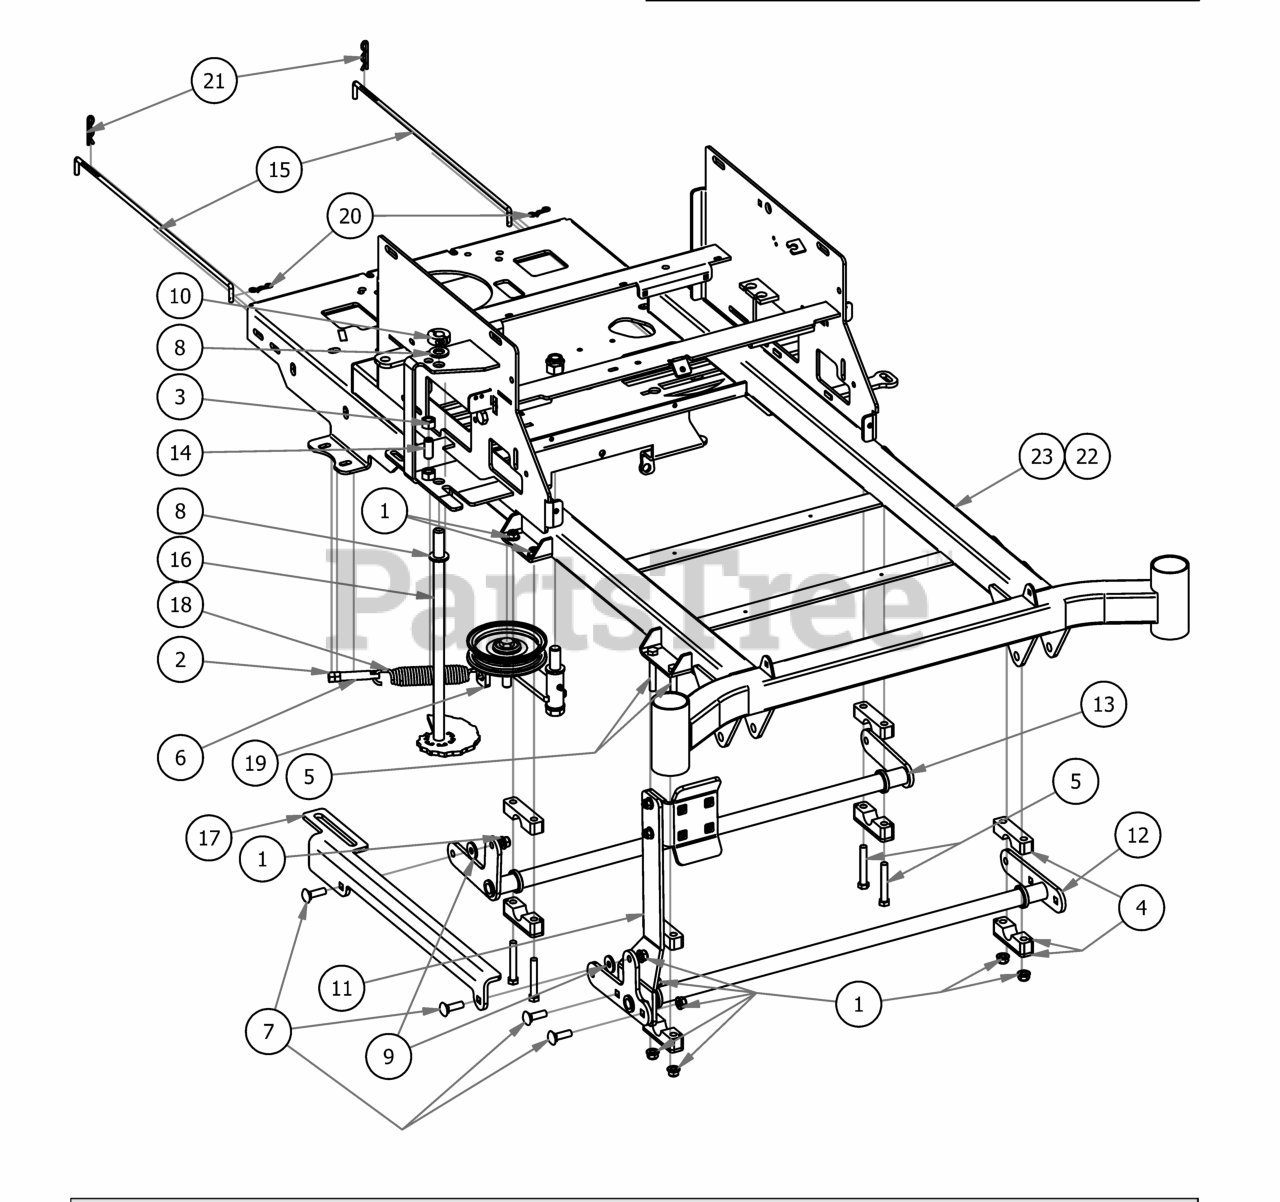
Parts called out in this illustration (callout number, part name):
1	3/8" Nylock Flange Nut
2	3/8-16 Hex Nut
3	1/2" Hex Nut
4	Pillow Block Kit
5	3/8-16 x 2 1/2" Hex Bolt
6	All Thread
7	3/8" x 1 1/4" Carriage Bolt
8	.630 ID x 1.122 OD x .142 THK Plastic Washer
9	.360 ID Plastic Washer
10	5/8" Split Collar
11	Foot Pedal Assembly
12	Actuator Bar Front- 2017 MZ/ZT
13	Actuator Bar Rear- 2017 MZ/ZT
14	Dial Rod Plunger
15	Neutral Rod
16	ZT Deck Height Bar Assembly
17	2017 MZ/ZT Actuator Linkage
18	Deck Idler Spring
19	ZT Pump Idler
21	Neutral Rod Clip
22	ZT 54" and 60" Frame
23	2017 MZ/ZT 42"-48" Frame
